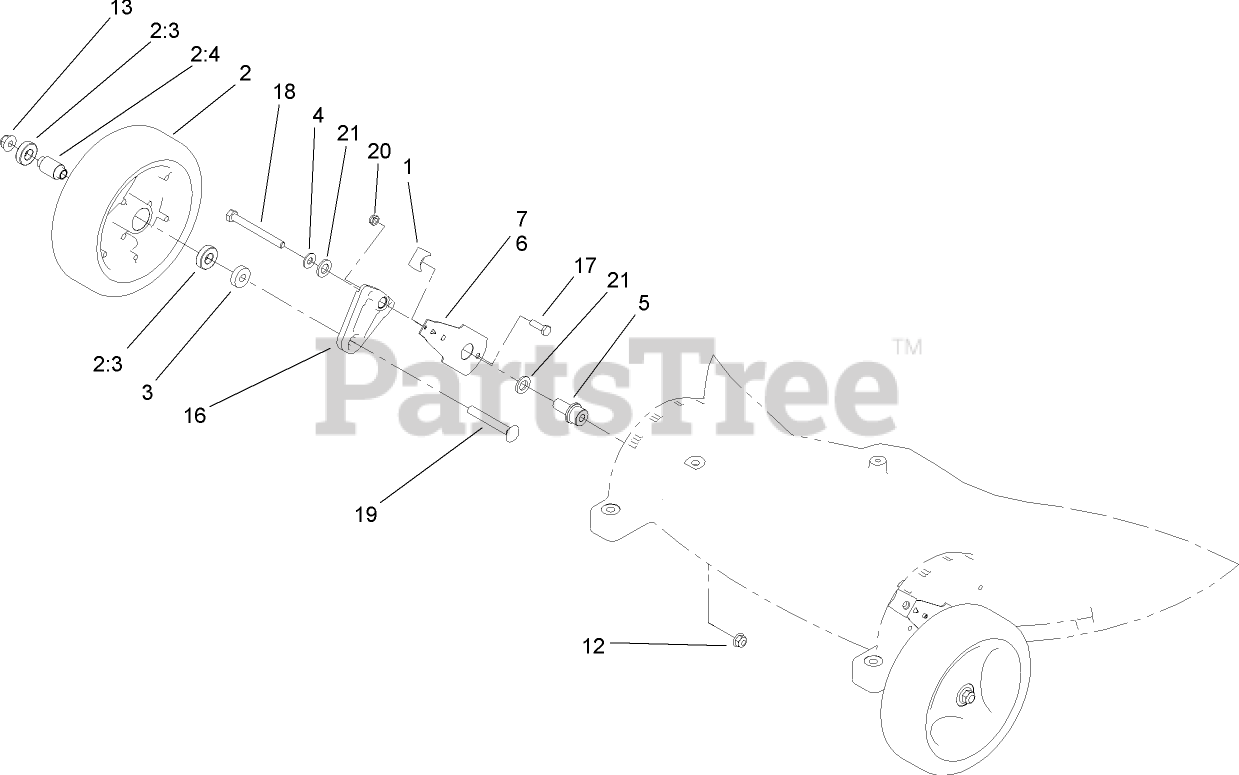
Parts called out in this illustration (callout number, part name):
1	KNOB-ARM
2	8 INCH WHEEL ASM
2:3	BEARING-WHEEL
2:4	SPACER-WHEEL, FRONT
3	SPACER
4	WASHER-FLAT
5	BUSHING-PIVOT, WHEEL
6	LH FRONT SPRING ARM ASM
7	RH FRONT SPRING ARM ASM
12	NUT-HF, NI
13	NUT-HF, NI
16	FRONT PIVOT ARM ASM
17	SCREW-HH
18	SCREW-HH
19	SCREW-CARR
20	NUT-LOCK, NI
21	WASHER-THRUST, NYLON
